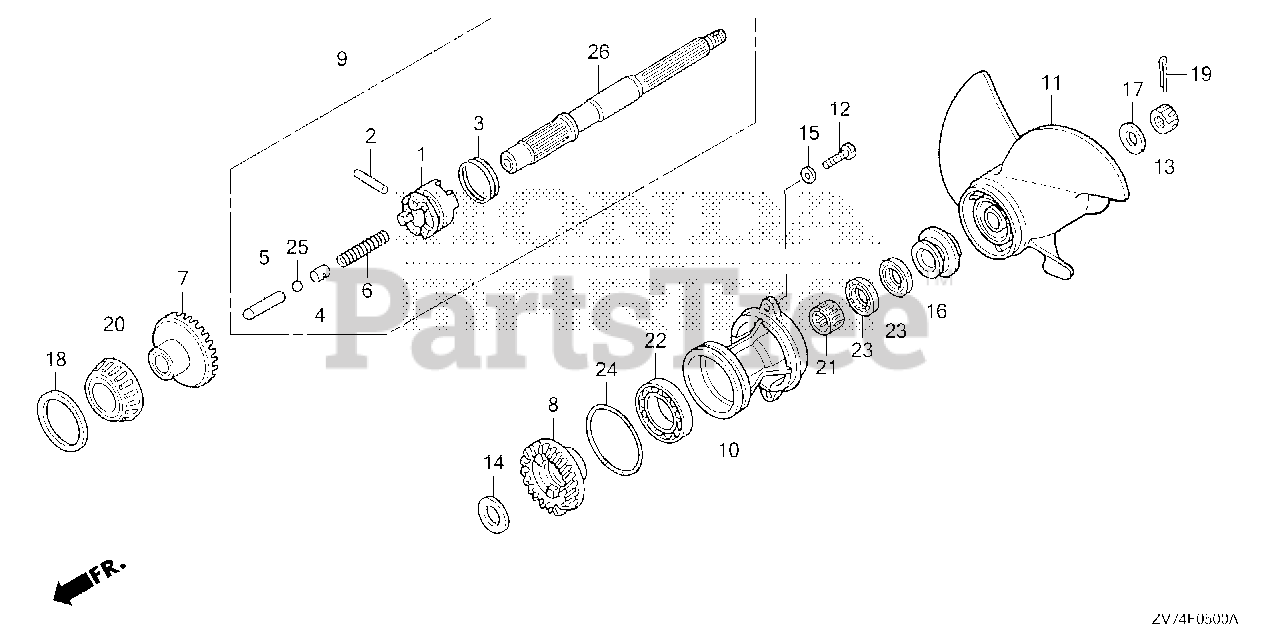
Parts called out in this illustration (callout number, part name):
1	SHIFTER, CLUTCH
2	PIN, SHIFTER
3	RING, CROSS PIN
4	HOLDER, SHIFTER PIN
5	SLIDER, SHIFT
6	SPRING, SHIFT
7	GEAR, FR. BEVEL
8	GEAR, RR. BEVEL
9	SHAFT ASSY., PROPELLER
10	HOLDER, PROPELLER SHAFT *NH282MU* (OYSTER SILVER METALLIC-U)
11	PROPELLER, THREE-BLADE (9-1/4X12) *NH283* (STIN GRAY)
12	BOLT, HEX. (6X20)
13	NUT, CASTLE
14	WASHER (22MM)
15	WASHER, PLAIN (6MM)
16	WASHER, PROPELLER THRUST
18	SHIM, FR. BEVEL (51X57X0.10) (A)
18	SHIM, FR. BEVEL (51X57X0.15) (B)
18	SHIM, FR. BEVEL (51X57X0.30) (C)
18	SHIM, FR. BEVEL (51X57X0.50) (D)
19	PIN, SPLIT
20	BEARING (32X58X17)
21	BEARING, NEEDLE (22X28X20)
22	BEARING, RADIAL BALL (32X58X13) (KOYO)
23	SEAL, WATER (22X35X7)
24	O-RING (64X3)
25	BALL, STEEL (#11) (11/32)
